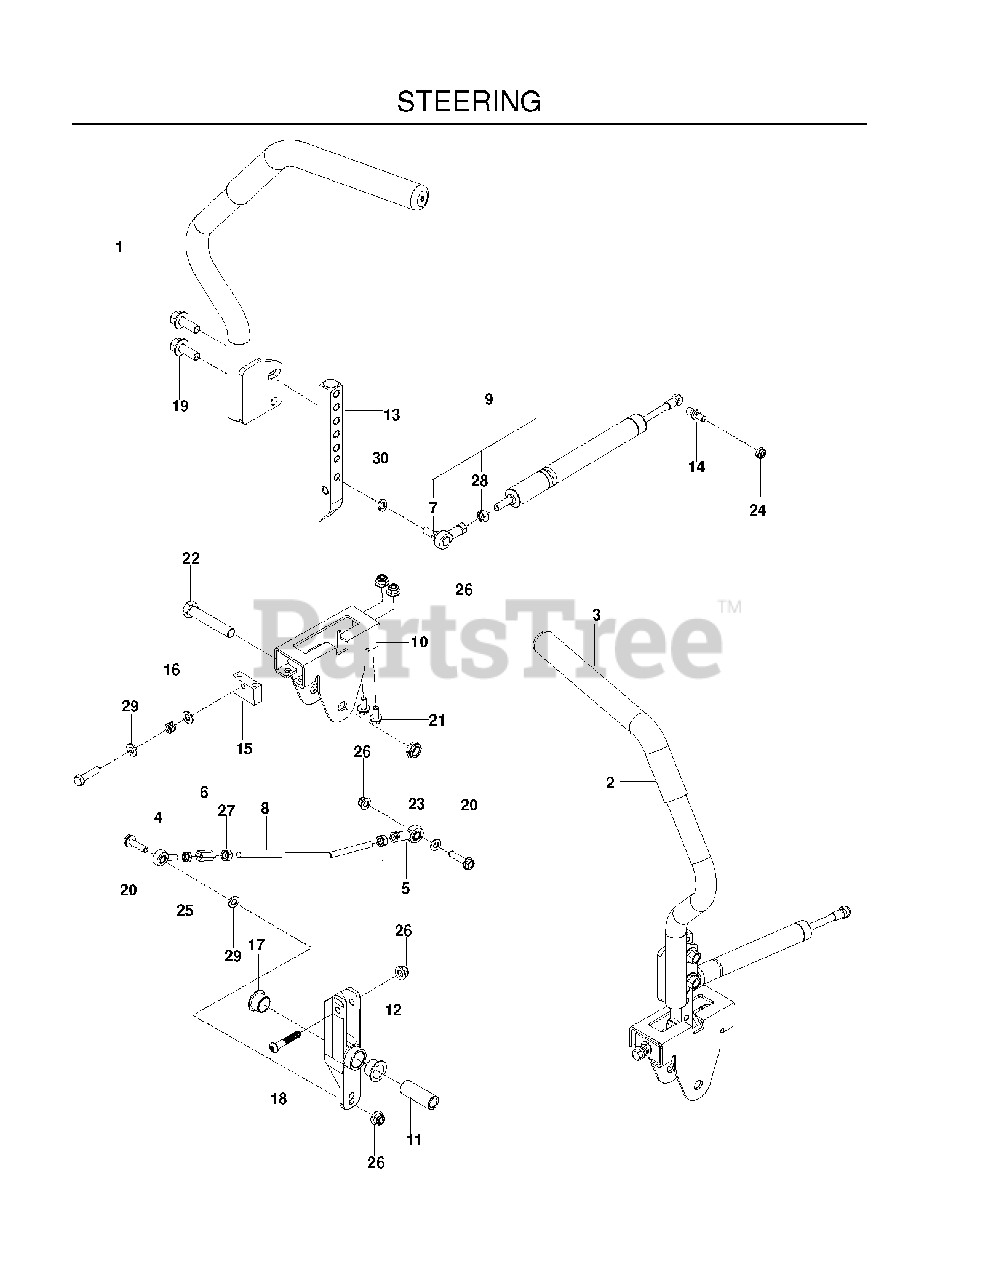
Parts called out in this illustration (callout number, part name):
1	LEVER, W/GRIP, RT
2	LEVER, W/GRIP, LT
3	GRIP - DRIVE LEVER
4	ROD END LH
5	RH ROD END
6	ROD END COUPLER
7	ROD END
8	ROD, CONTROL
9	ASSEMBLY, DAMPENER
13	LEVER, MOTION
14	10MM BALL STUD
17	BEARING, FLANGE
19	HHFS 3/8-16 X 1 GRD 5 ZD
20	HHFS 5/16-18 X 1.25 TPBLT GD 5
21	HHFS 5/16-18 X 3/4
22	HCS 1/2C X 2 3/4
23	NUT 1/2-13 HEX JM NYL
24	5/16-18 THIN PROF NY
25	NUT 5/16F LEFTHAND
26	5/16-18 NYLOC FLANGE NUT
27	NUT 5/16F
28	NUT M8 X 1.25 STD HEX
29	FLAT WASHER 5/16 SAE
30	WASHER 5/16 LOCK
